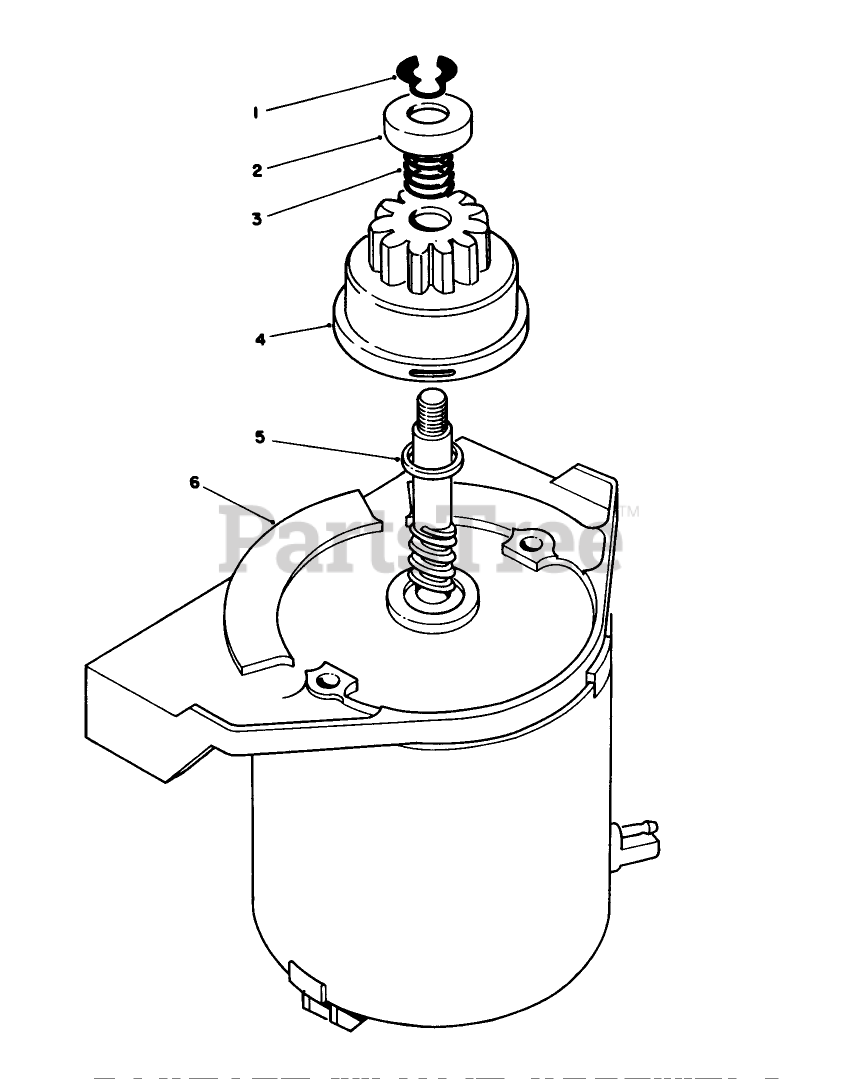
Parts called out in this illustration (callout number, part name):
1	RING-RETAINING
2	PINION STOP
3	COMPRESSION SPRING
4	PINION ASM
5	SPACER
6	END FRAME ASSY, MOTOR
